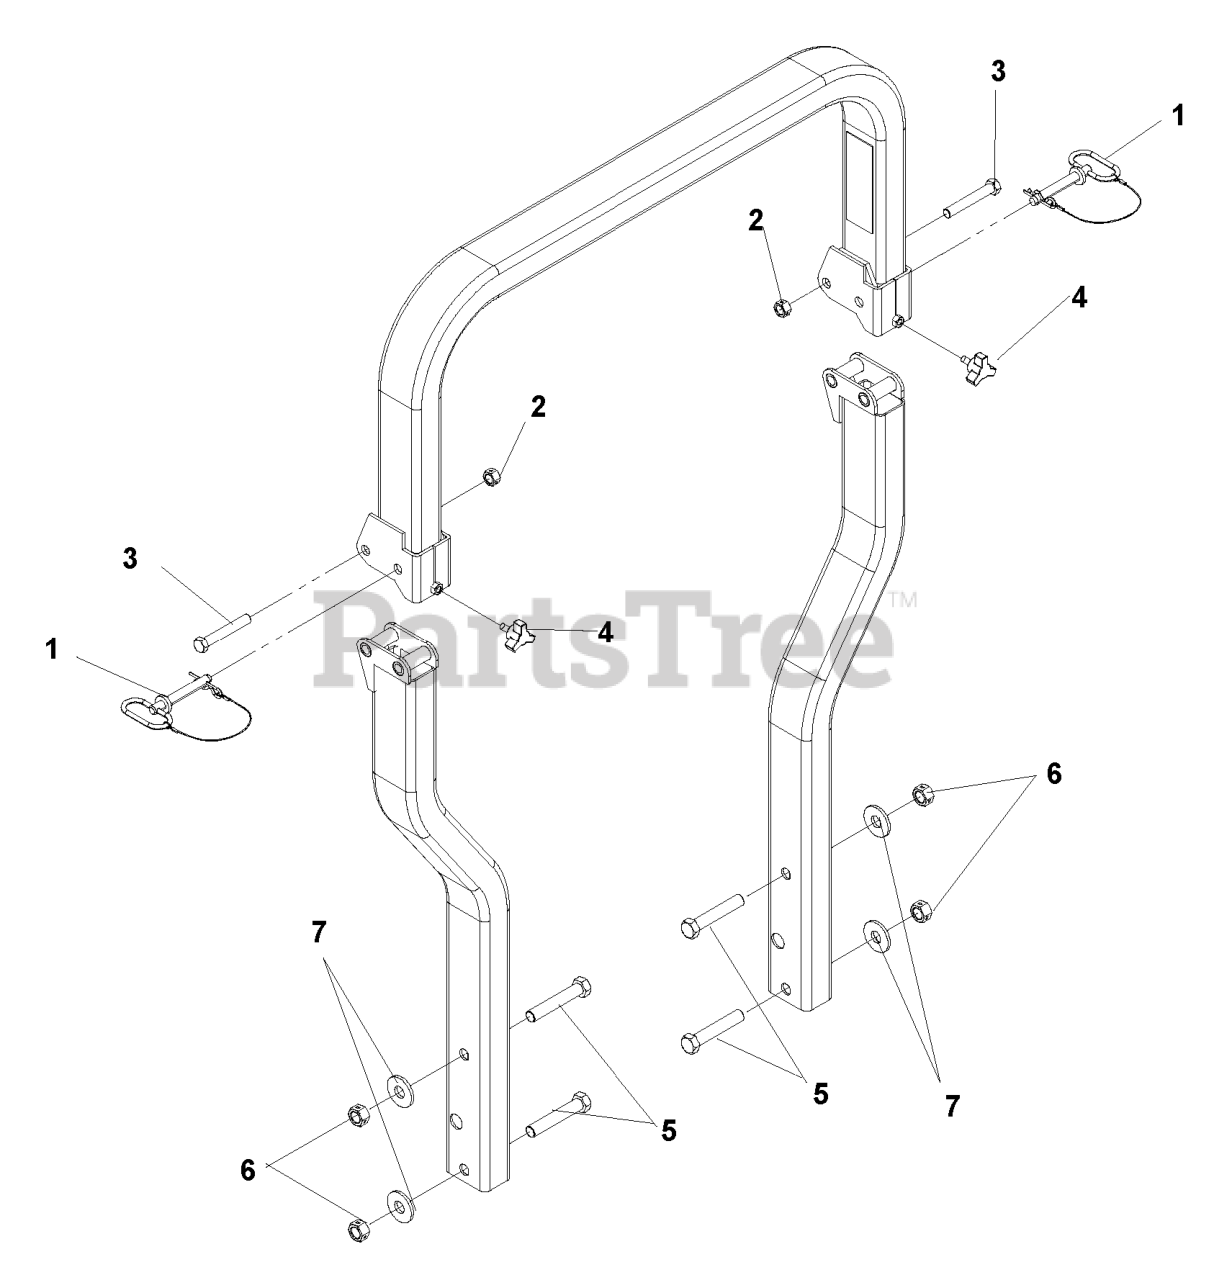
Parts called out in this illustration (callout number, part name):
1	PIN, 1/2" W/LANYARD
2	NUT 1/2-13 HEX CNTRLK GR 5 ZD
3	HCS 1/2C X 3 1/4
4	KNOB W/STUD
5	HCS 5/8-11 X 3 GR 5 ZD
6	NUT 5/8-11 HEX CNTRLK ZD
7	WASHER, 5/8 FLAT
